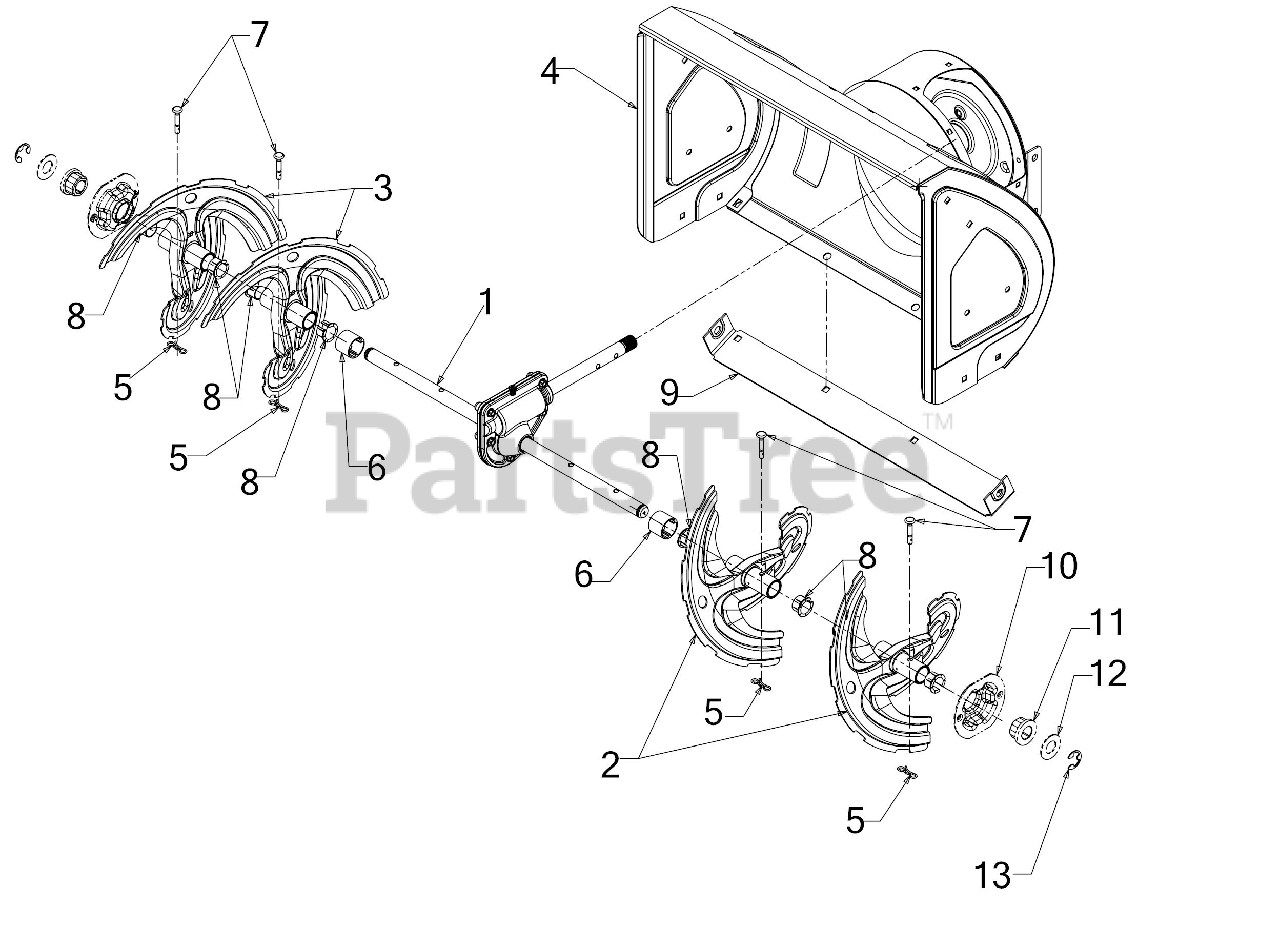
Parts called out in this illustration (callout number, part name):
1	22" AUGER GEARBOX ASSEMBLY
5	BOW TIE COTTER PIN 1/4-5/16
6	SPACER 1.25OD x .75ID X1.00 LG
7	SHEAR PIN .25 x 1.50 GR2
8	FLANGE BUSHING
11	FLANGE BEARING
12	FLAT WASHER .760ID X1.49OD x .06
13	E-RING
